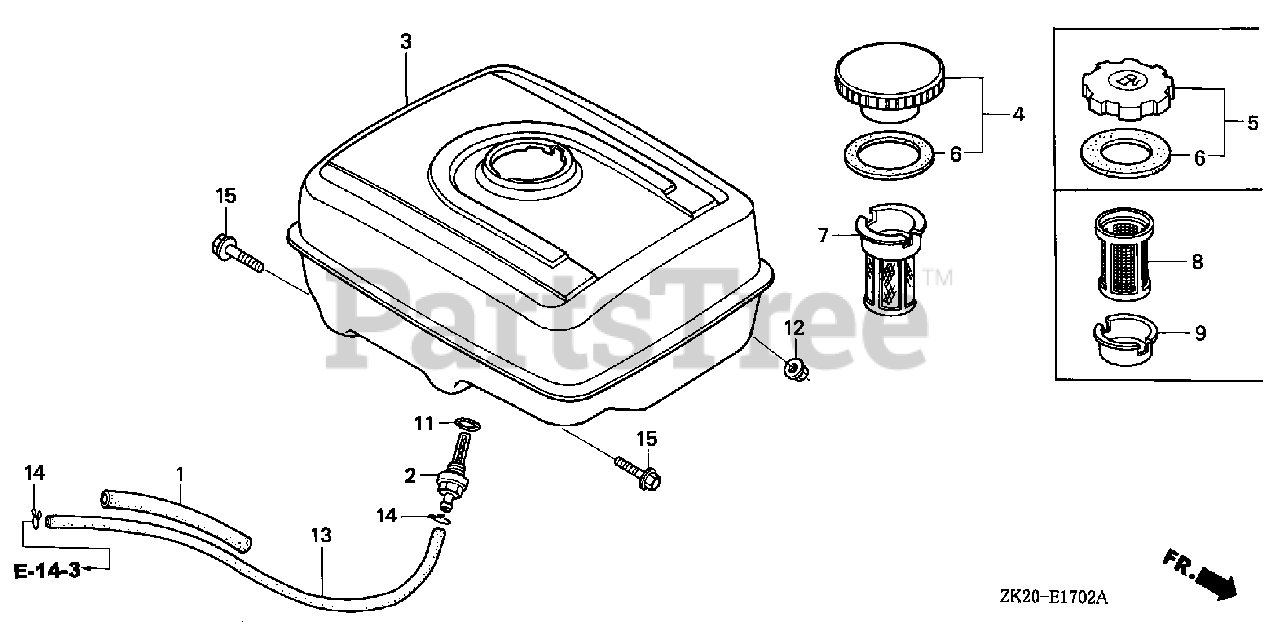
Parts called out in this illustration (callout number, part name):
1	RUBBER, SUPPORTER (107MM)
2	JOINT, FUEL TANK
3	TANK, FUEL *NH31* (MCKINLEY WHITE)
3	TANK, FUEL *NH1* (BLACK)
5	CAP, FUEL FILLER
6	GASKET, FUEL FILLER CAP
7	FILTER, FUEL
11	O-RING (13.5X1.5) (ARAI)
12	NUT, FLANGE (8MM)
13	BULK HOSE, FUEL (4.5X3000) (4.5X222)
14	CLIP, TUBE (B8)
15	BOLT, FLANGE (8X25)
